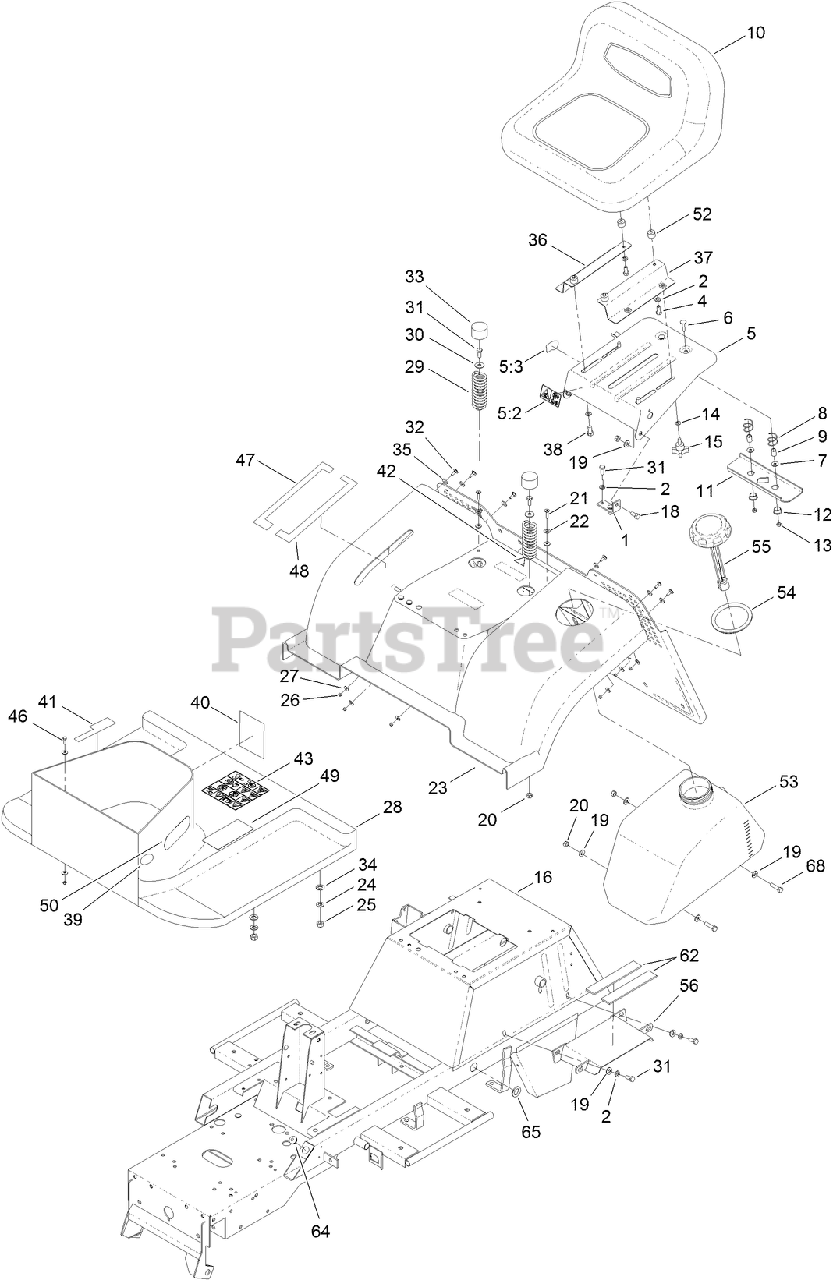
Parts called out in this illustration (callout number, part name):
1	BRACKET-SUPPORT, SEAT
2	WASHER-LOCK
4	SCREW-HH
5	SEAT PAN ASM
5:2	DECAL-DANGER
5:3	DECAL-SWITCH
6	BOLT-CARRIAGE
7	WASHER-FLAT
8	SPRING-SEAT
9	SPACER-SPLIT
10	SEAT ASM
11	BRACKET
12	BUSHING
13	NUT-LOCK
14	WASHER-SPRING
15	KNOB-ADJUSTMENT
18	SCREW-SUPPORT, SEAT
19	WASHER-PLAIN
20	NUT-LOCK, NI
21	SCREW-HSFH
24	WASHER-FLAT
25	NUT-LOCK, NI
26	NUT-LOCK
27	WASHER-FLAT
28	FOOTREST ASM
29	SPRING-SEAT
30	WASHER-PLAIN
31	SCREW-HH
32	BOLT-CARRIAGE
33	CAP-HUB
34	WASHER-RUBBER
35	WASHER-RUBBER
36	BRACKET-SEAT, RH
37	BRACKET-SEAT, LH
38	SCREW-HHF
39	DECAL-BRAKE, PARKING
40	DECAL-STARTING
41	DECAL-OPERATION, HYDRO
42	DECAL-BAG TO FRAME
43	DECAL-DANGER
46	SCREW-HH
47	DECAL-HOC, LH
48	DECAL-HOC, RH
49	DECAL-OPERATION
50	DECAL-TOWER
52	SHIM-SEAT
53	TANK-FUEL
54	PROTECTOR-NECK, FILLER
55	CAP-FUEL
56	BRACKET-TANK, FUEL
62	STRIP-RUBBER, FUEL TANK
64	GROMMET
65	GROMMET
68	SCREW-HH
